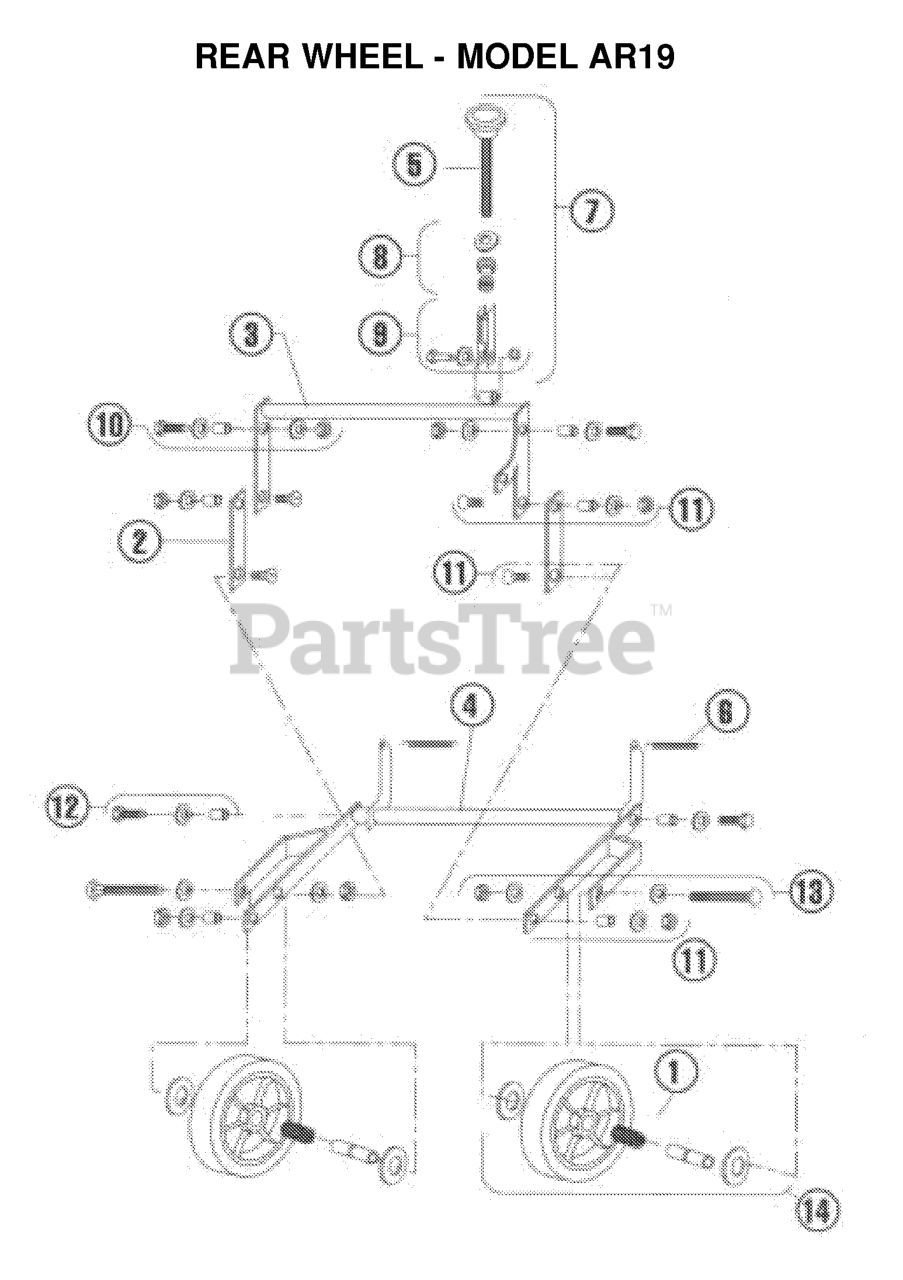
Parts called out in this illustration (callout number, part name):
1	ROLLLER BEARING
2	LIFT ARM LINK LWR ORN
3	TORQUE ARM
4	KIT WHEEL CARRIAGE ORANGE
5	KNOB, DEPTH/STABILITY
6	SPRING, IDLER CAM, 3 3/4"
7	KIT DEPTH CONTROL STABILITY
8	KNOB SPRING KIT
9	BRACKET KIT
10	FASTENER KIT
11	FASTENER KIT, LINKAGE
12	FASTENER KIT
13	BOLT KIT
14	REAR WHEEL, COMPLETE
